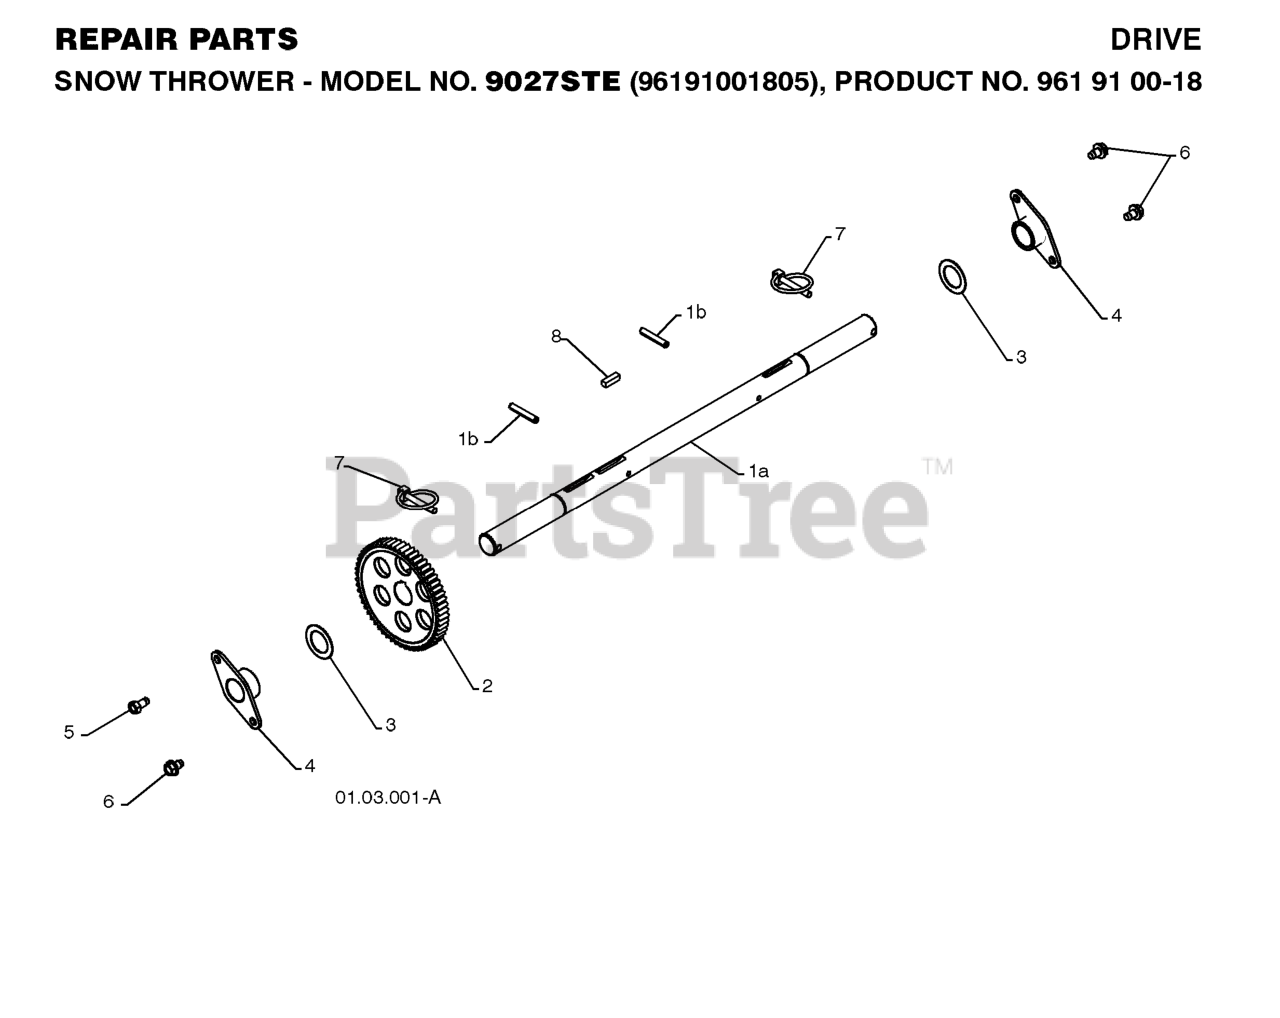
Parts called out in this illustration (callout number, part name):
1	AXLE.ASM.SHAFT.W/ROLLPIN.PS
1A	SHAFT.AXLE.POWER.STEERING
1B	PIN.ROLL.3/16
2	GEAR, AXLE (58T)
3	WASHER TRUST 1"
4	BEARING, AXLE
6	Screw 5/16-18 x 1/2 Hex, Self Tapping 5/16-18 x 1/2
7	PIN KLIK, 1/4
8	KEY, SQUARE 1/4 X .875
